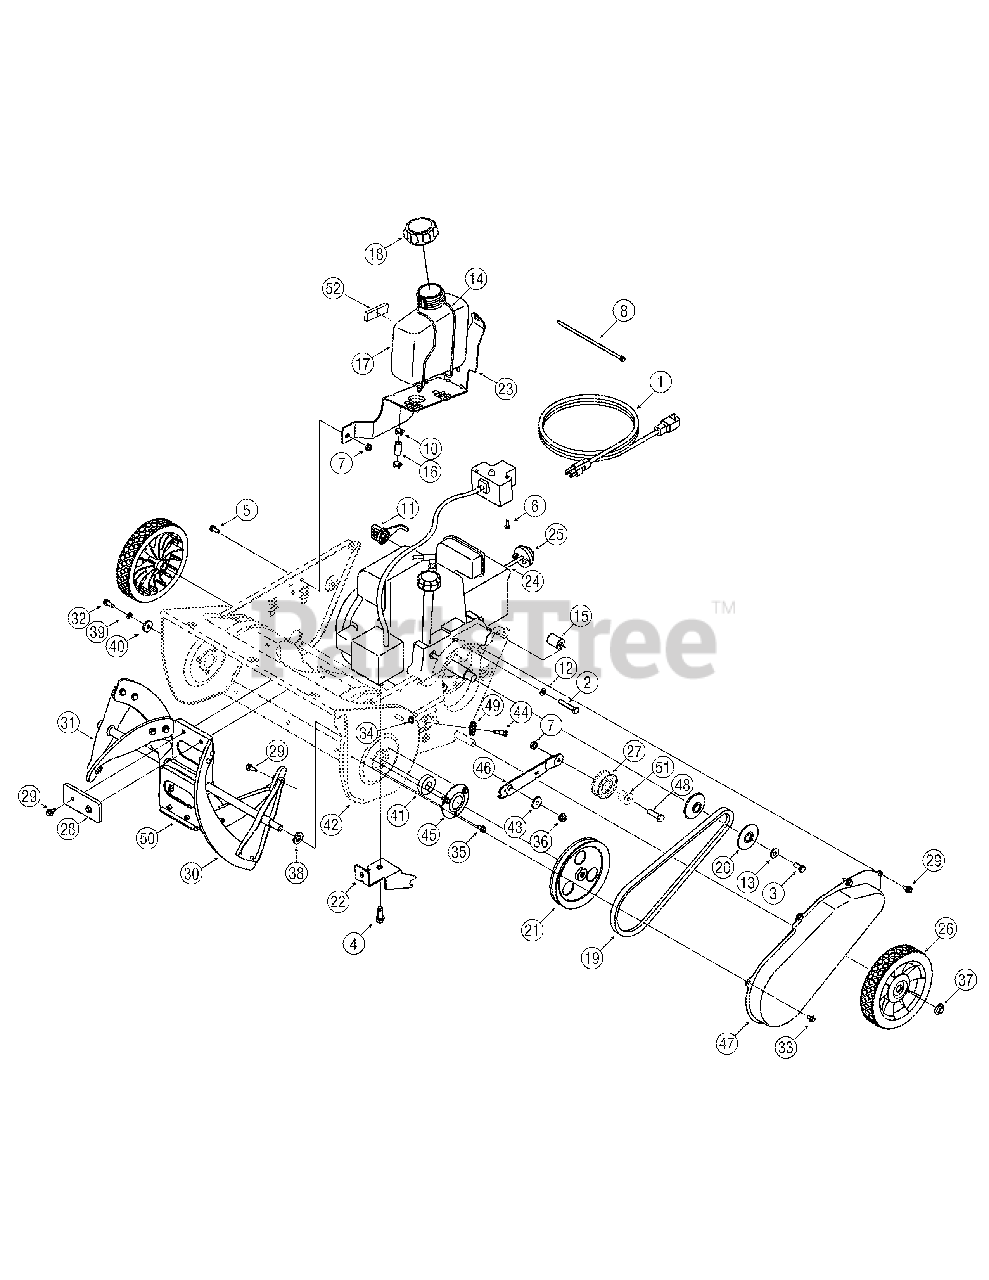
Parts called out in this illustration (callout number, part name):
1	Extension Cord 10 Ft.
2	Hex Bolt 5/16-24 x 1.75
3	Hex L-Bolt 5/16-24 x .75 Gr. 5
4	Hex Wash HD Tap Scr 3/8-16 x .88
5	Hex Bolt 1/4-20 x .62 Gr. 5
6	Hex Wash B-Tapp Scr #10 x .62" Lg.
7	Hex L-Flanged Nut 1/4-20 Gr. F Nylon
8	Push Mount Tie
9	Push Speed Nut
10	Hose Clamp
11	Choke Knob
12	L-Wash 5/16 ID
13	Flat Washer .340 ID x .872 OD x .060
14	Gas Tank Wire Support
15	Spacer .875 x .320 x 1.10
16	Fuel Line
17	Fuel Tank 2 Quart
18	Cap-Fuel
19	V-Belt 1/2 x 35.0" Lg.
20	Pulley Half .625 ID x 2.25 OD
21	Pulley 1/2 x 6,0" OD
25	Primer
26	Wheel, 7.0 x 1.5 Lug
27	Idler Pulley (1/4" hole)
28	Rubber Paddle
29	Hex B-Tap Scr 1/4-28 x .25" Lg
30	Rubber Spiral-Crescent
32	Thd Forming Scr. 1/4-20 x .75 Lg.
33	Hex Wash HD Tapp Scr 1/4-20 x .375
34	Hex Ins Jam L-Nut 1/4-28
35	Hex Tap Scr. 1/4-14 x .375" Lg.
36	Flange Locknut 5/16-18 Gr. F, Nylon
37	Push Cap x 1/2" Rod
38	Flat Washer .50 ID x 1.00 OD x .125
39	L-Wash 1/4 ID
40	Flat Washer .25 ID x .93 OD x .125
41	Ball Bearing .625 x 37 x 12.63
43	Shoulder Spacer .25 THK
44	Hex Shld.Scr.1/4-28 x .375
48	Hex Screw 1/4-20 x 1.25 Gr. 5 Special
49	Cable Guide Roller
50	Auger Assembly
51	Shld. Spacer .260 x .785 x .538
52	Tape
